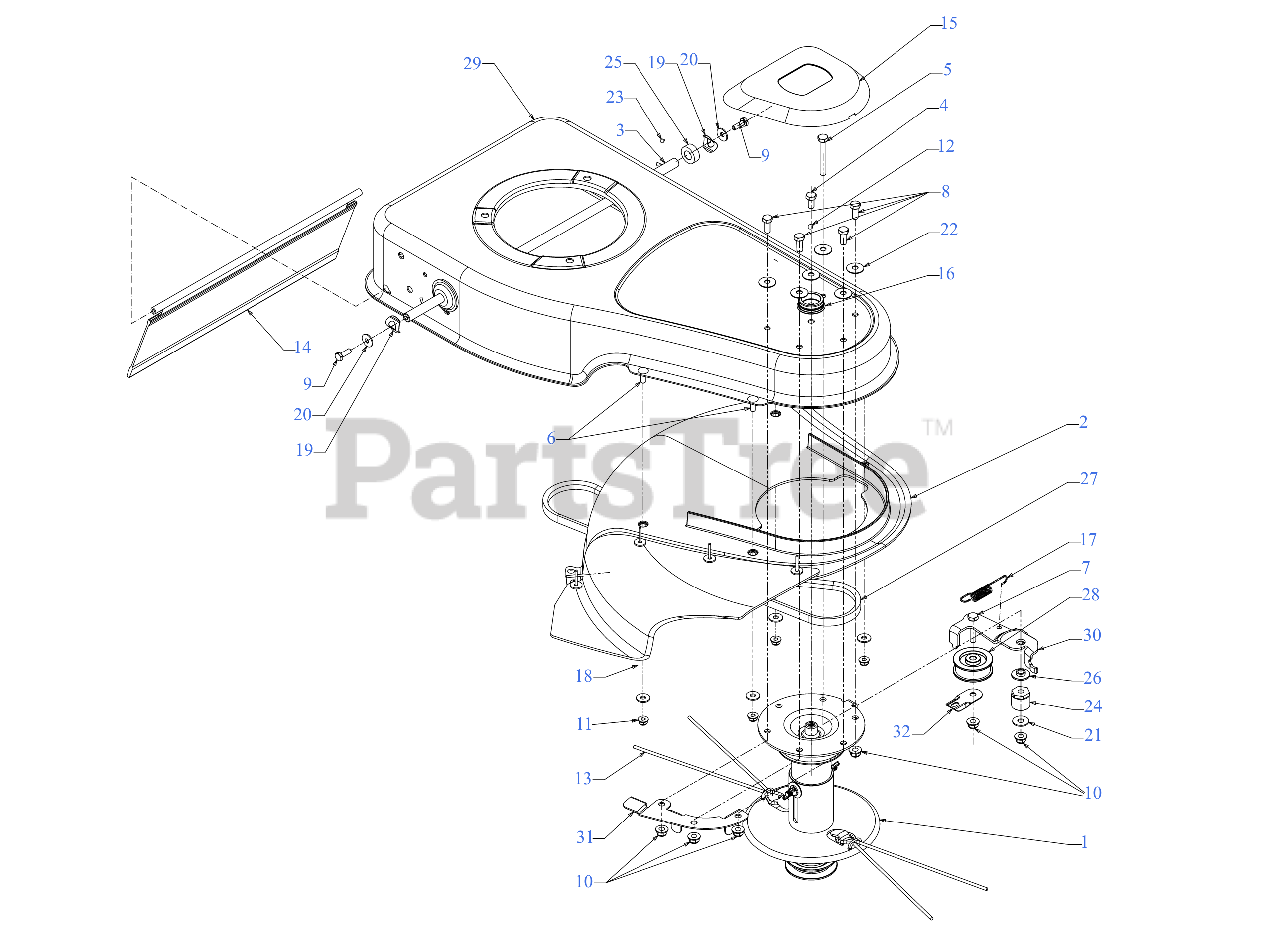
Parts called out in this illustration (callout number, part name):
1	SPINDLE ASSEMBLY
2	22" DEFELECTOR ASSEMBLY
3	AXLE ASSEMBLY
4	HEX SCREW 5/16-24 x .62
5	HEX SCREW 5/16-18 x 2.25 GR5
6	SCREW 1/4-20 x .75 GR5
7	SCREW 5/16-18 x 1.5 LG
8	SCREW 5/16-18 x .75 GR5
9	SCREW 1/4-20X.75 GR5
10	FLANGE LOCK NUT 5/16-18
11	FLANGE LOCK NUT
12	NOT SERVICEABLE
13	TRIMMER LINE: 10 P
14	TRIMMER TRAILSHIELD
15	COVER TRIM
16	COVER TRIM RETAINER
17	EXTENSION SPRING .500 OD x 3.375
18	FLAT WASHER .28 ID x .74 OD x .063
19	SPRING WASHER .50 x 1.0 x .022
20	SPRING WASHER BELL
21	FLAT WASHER
22	BELL WASHER
23	NOT SERVICEABLE
25	SPACER .51
26	IDLER SPACER
27	V-BELT 4L x 44.6"
28	IDLER PULLEY
30	IDLER BRACKET
